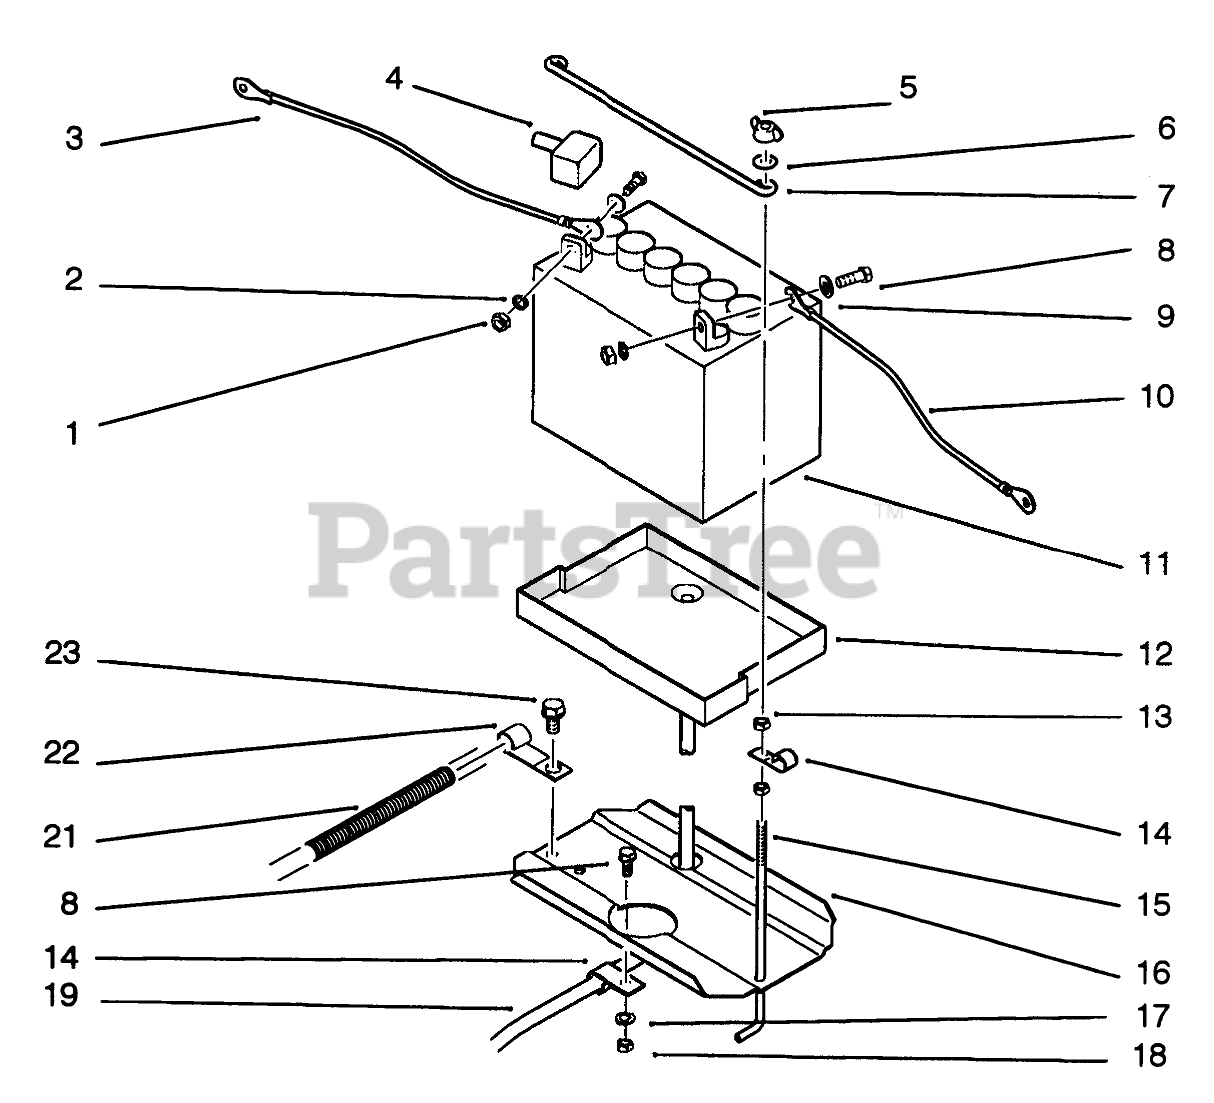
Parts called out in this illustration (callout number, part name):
1	NUT-HEX
2	Washer
3	ASS'Y-WIRE
4	Boot
5	NUT-WING
6	WASHER-FLAT
7	ROD-BATTERY HOLD DWN
8	SCREW-HH
9	WASHER-FLAT
10	WIRE -BLACK
11	Battery
12	TRAY-BATTERY
13	Nut
14	CLAMP
16	Tray
17	WASHER-FLAT
18	NUT-LOCK, NI
19	TUBE-21" BATTERY DRAIN
21	WIRING-HARNESS
22	CLIP
23	Screw
